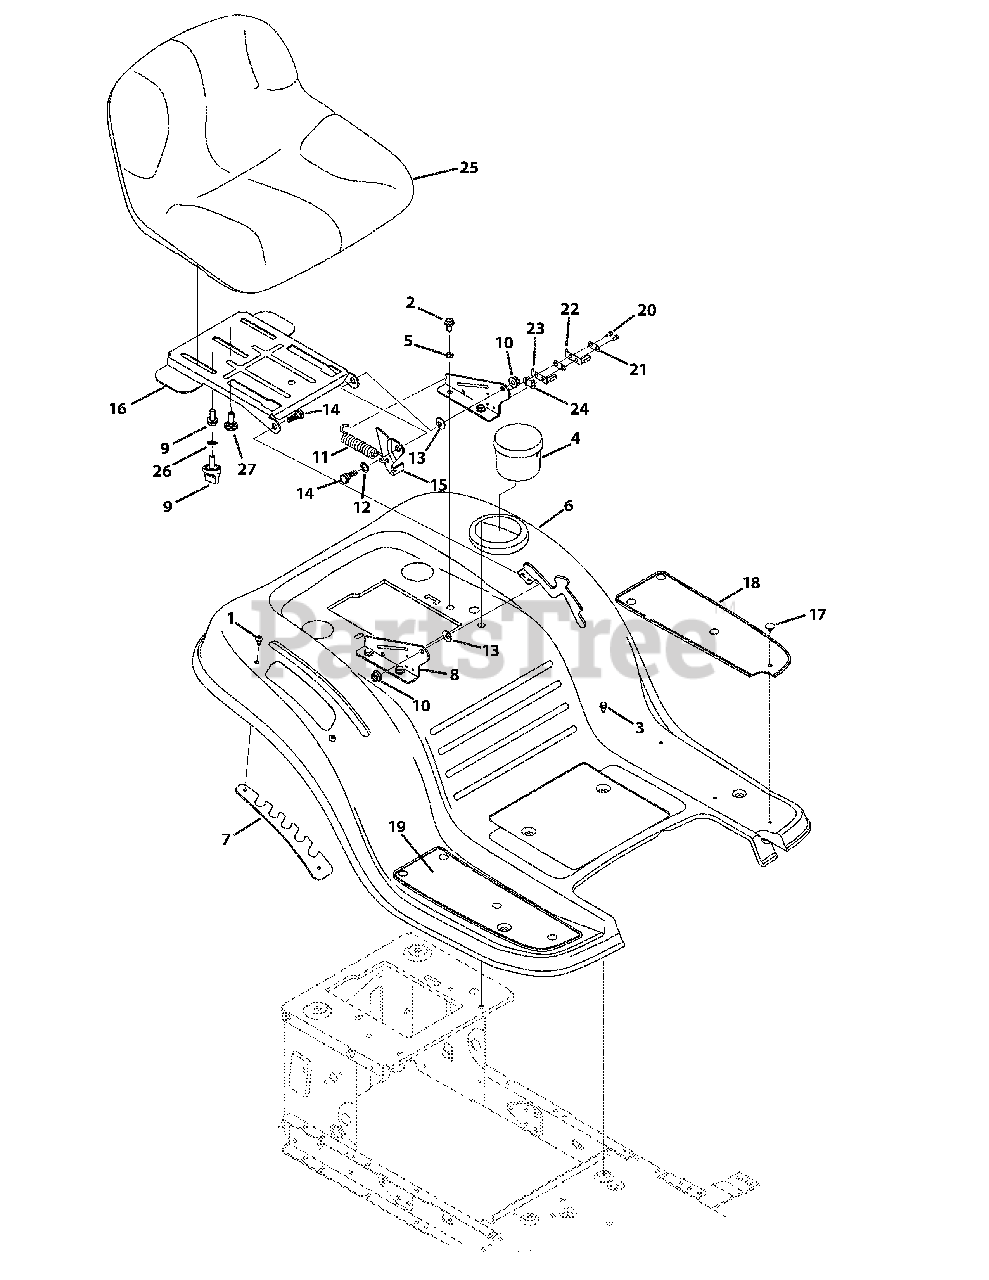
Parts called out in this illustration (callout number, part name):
1	Screw, 1/4-20 x .500
2	Screw, 5/16-18 x .750
3	Screw Pan Torx Head, 1/4-20 x .500
4	Cup Holder
5	Lock Washer, 5/16
6	Fender - Black Jack
6	Fender - Red
7	Lift Adjuster Bracket
8	Seat Mount Bracket
9	Hex Flange, 3/8-16 x .875
9	Knob
10	Flangelock Nut, 5/16-18
11	Extension Spring
12	Flat Washer, .510x .750 x .033
13	Bell Washer, .340 x .872 x .060
14	Shoulder Screw, 5/16-18 x .437 x .268
15	Lift Seat Bracket
16	Pivot Seat Manual Adjust Bracket
17	Ratchet Clip, .250 x .500
18	Foot Pad, LH
19	Foot Pad, RH
20	Screw, 8-18 x .500
21	Insulator Plate
22	Outer Seat SPring
23	Inner Seat Spring
24	Insulator Boss Plate
25	Medium Back Seat
25	High Back Seat
25	Ultra High Back Seat
26	Lock Washer
27	Screw., Shldr., .625 x .145 x 3/8-16
